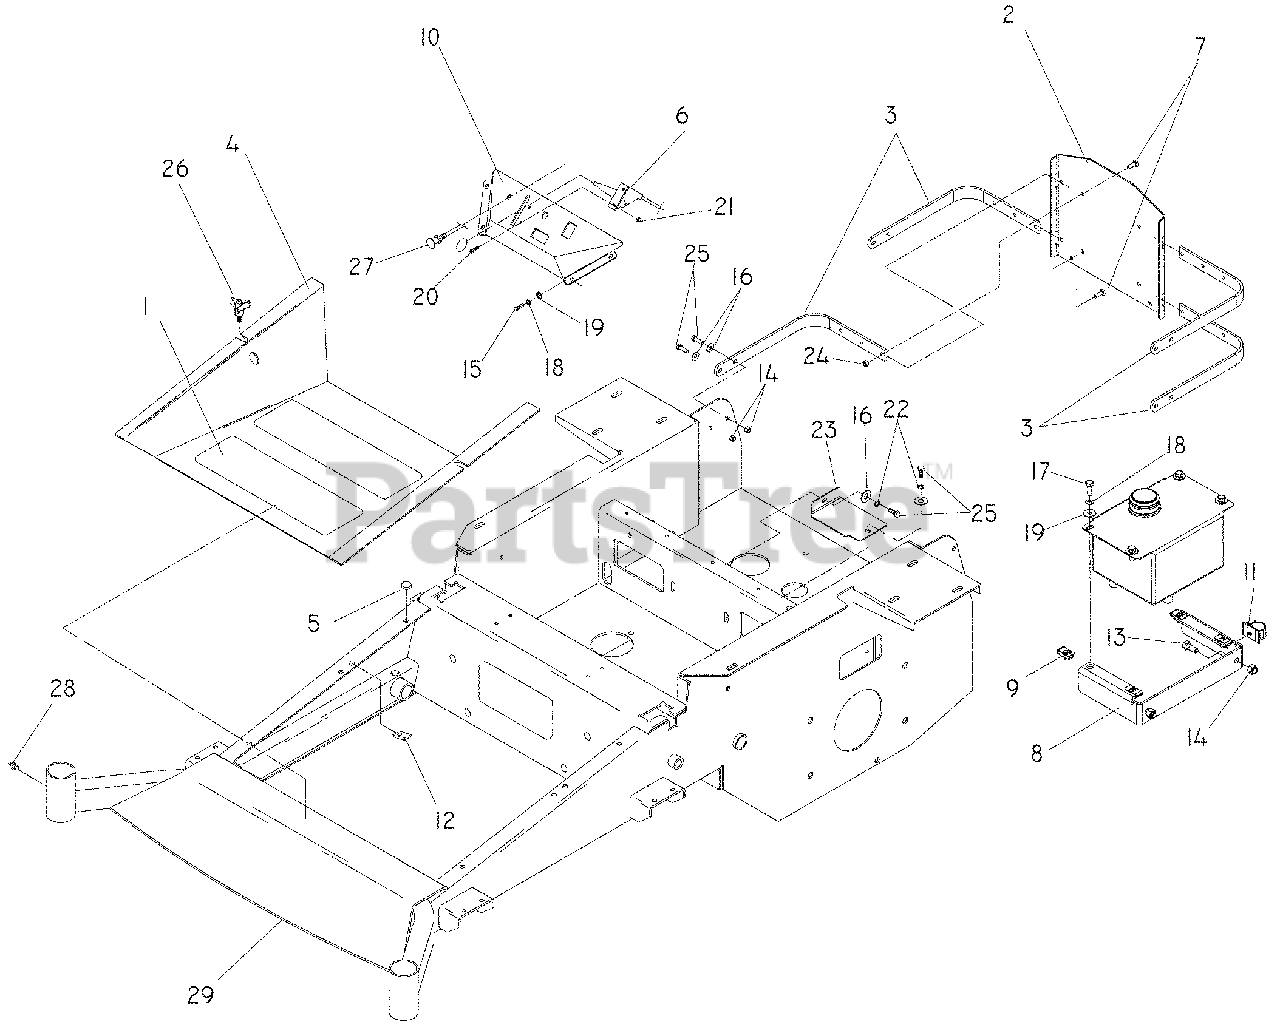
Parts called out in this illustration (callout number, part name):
1	FLOOR PAN PAD
2	XP GUARD, BLACK
3	STRAP, BLACK
4	FOOT PLATE
6	THROTTLE CABLE
7	RHSNB 5/16-18 x ¾ ZD
8	TANK MOUNT
9	"U" TYPE RETAINER ¼C
11	CLIP, PUSH MOUNT WIRE
12	"U" CLIP 5/16C
13	HCS, 5/16 -18 X ¾
14	NUT 5/16-18 HEX NYLOC
15	TFS ¼C x 5/8
16	WASHER, 5/16 STD FLT
17	HCS, ¼ - 20 x ¾
18	LOCKWASHER ¼
19	WASHER ¼ FLAT
20	HCS 10-24 x ½
21	NUT 10-24 NYLOC
22	WASHER 5/16 LOCK
23	IDLER COVER PAINTED
24	NUT 5/16-18 CENTERLOCK
25	HCS 5/16-18 x 1
26	KNOB W/STUD
27	CHOKE CONTROL
29	FRAME, 52"/61" for Serial No. 074439861 and after
